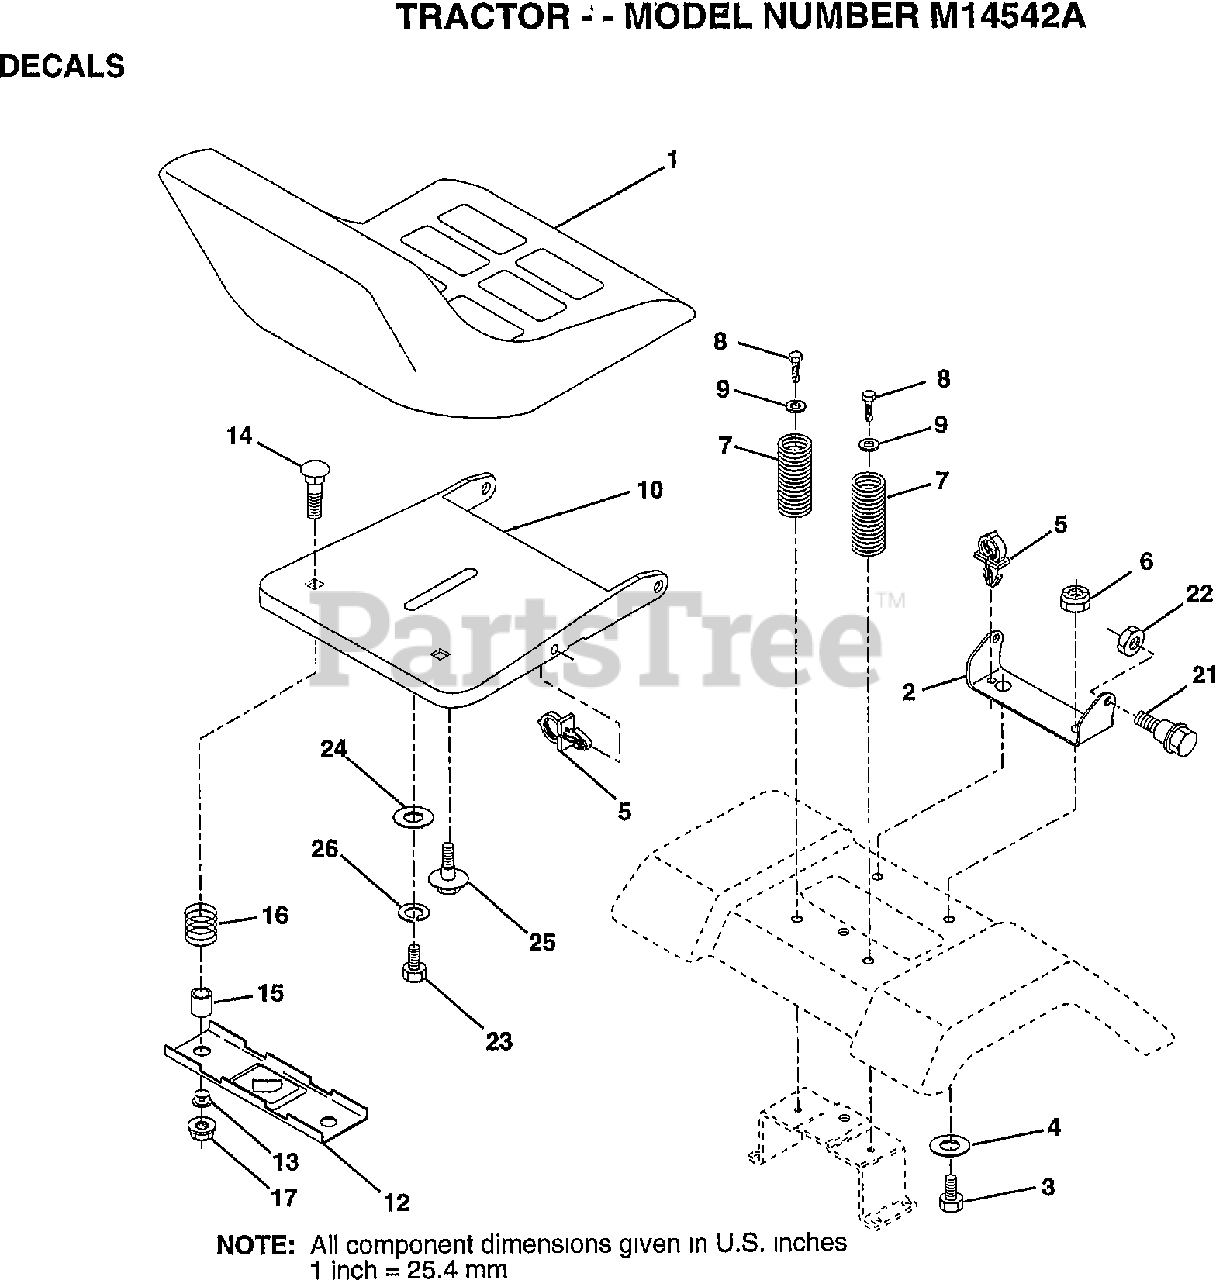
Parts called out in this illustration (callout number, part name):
2	BRACKET PVT SEAT
3	BOLT
4	WASHER PM
5	CLIP.PUSH-IN.HING
6	NUT
7	SPRING COMPRESSIO
8	SCREW GTV
9	WASHER
10	PAN-SEAT
12	BRKT SWITCH
13	BUSHING
15	SPLIT SPACER
16	SPRING
21	"BOLT,SHOULDER"
22	NUT
23	BOLT
24	WASHER
25	"BOLT,SHOULDER"
26	LOCKWASHER
